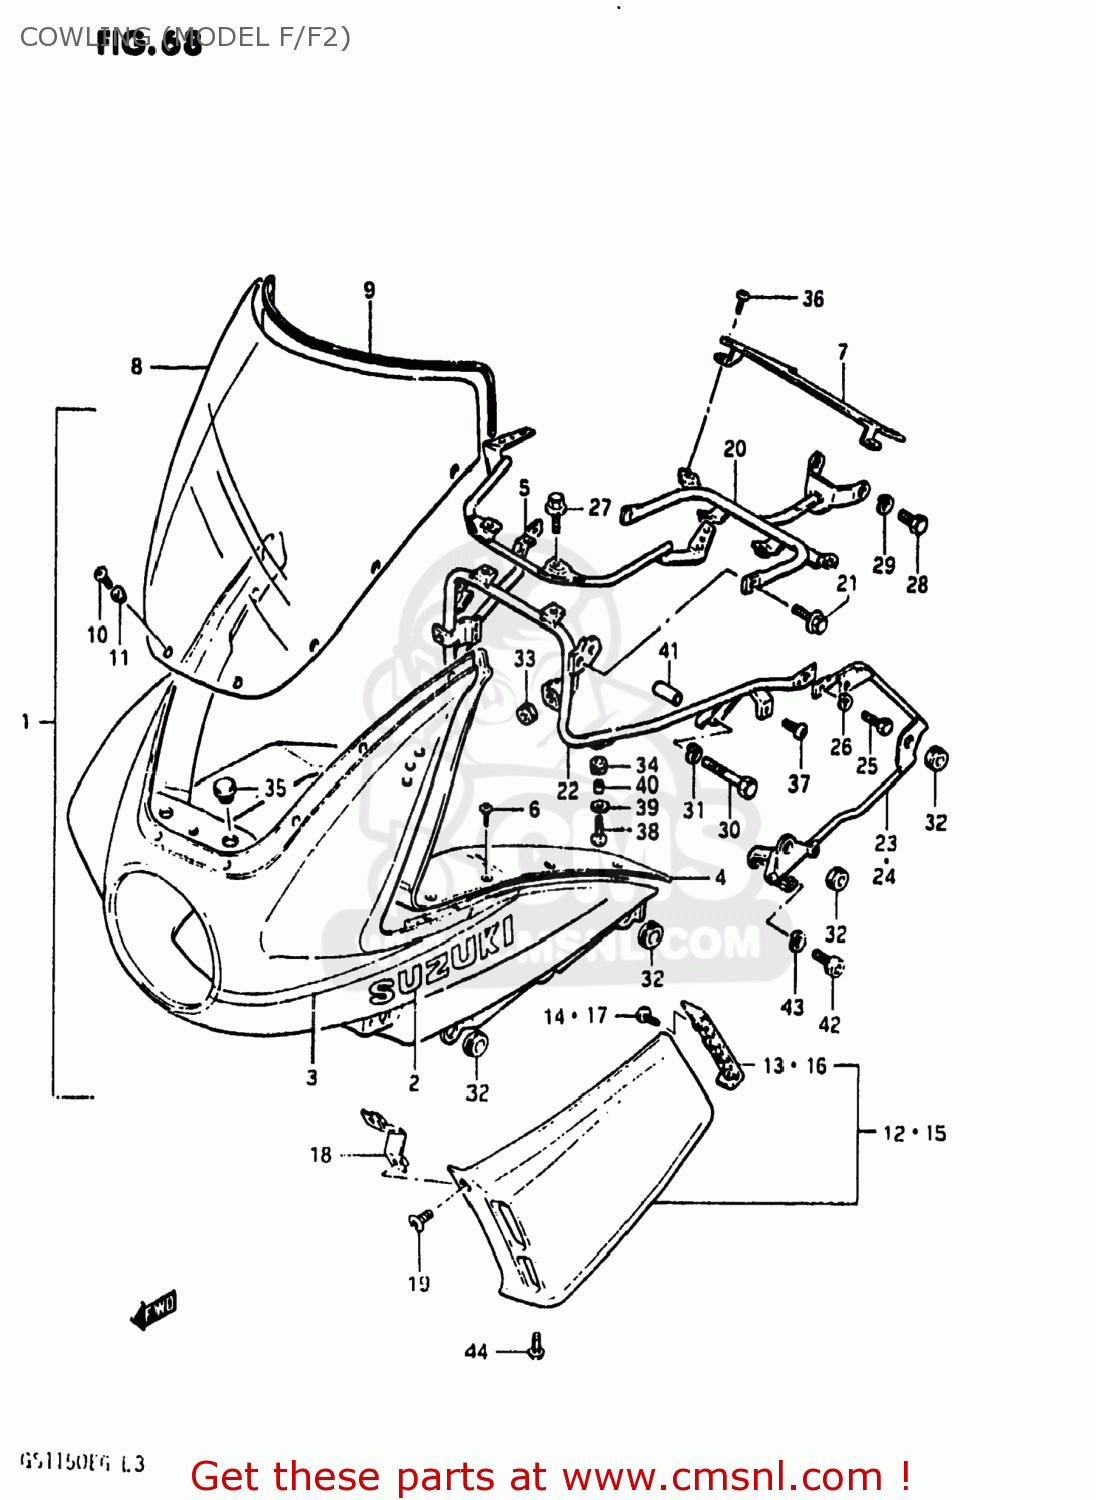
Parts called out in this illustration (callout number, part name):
1	COWLING ASSEMBLY
2	EMBLEM
3	TAPE SET,COWLING
4	PANEL,COWLING
5	BRACE,COWLING BODY
6	SCREW, PANEL
7	COVER,METER,REAR
8	WINDOW,COWLING
9	MOLDING COWLING
10	SCREW(5X20)
11	CUSHION
12	COVER,COWLING SIDE,RIGHT
13	PANEL,COWL SIDE COVER RR RH
14	SCREW
15	COVER,COWLING SIDE,LEFT
16	PANEL,COWLING SIDE COVER
17	SCREW
18	BRACE,SIDE,FRONT
19	SCREW
20	BRACE,COWLING,FRONT
21	BOLT
22	BRACE,COWL RR
23	BRACE,COWLING SIDE,RIGHT
24	BRACE,COWLING SIDE,LEFT
25	BOLT 6X16
26	WASHER,LOCK
27	BOLT
28	BOLT
29	WASHER,LOCK,8.
30	BOLT
31	WASHER,LOCK,8.
32	CUSHION
33	CUSHION
34	CUSHION
35	PLUG(OD:22)
36	SCREW
37	SCREW 6X12
38	SCREW, CENTER
39	WASHER(6.5X18X1)
40	SPACER (6.1X9X9)
41	SPACER (8.6X13.8X35)
42	BOLT
43	WASHER,LOCK,8.
44	SCREW
